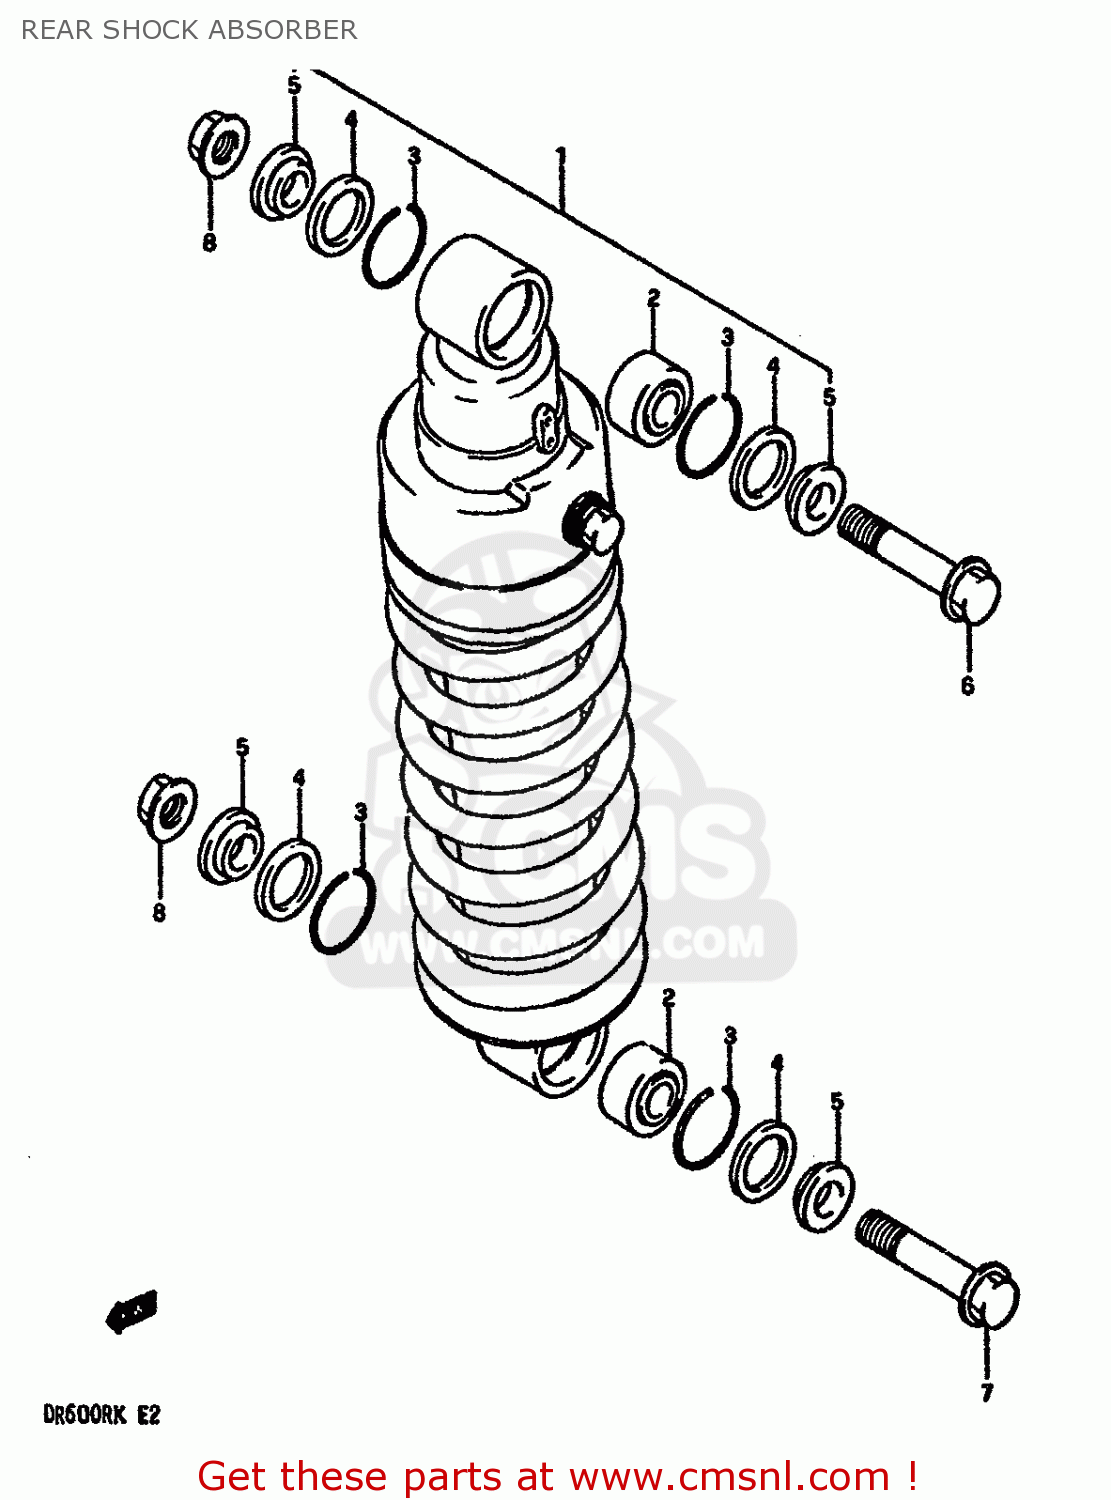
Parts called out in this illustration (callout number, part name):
1	ABSORBER ASSY, REAR SHOCK (BLUE)
2	BEARING,REAR SHOCK ABSORBER
3	RING
4	SEAL,DUST RR SHOCK ABSORBER
5	COLLAR
6	BOLT(10X54)
7	BOLT(10X52)
8	NUT
